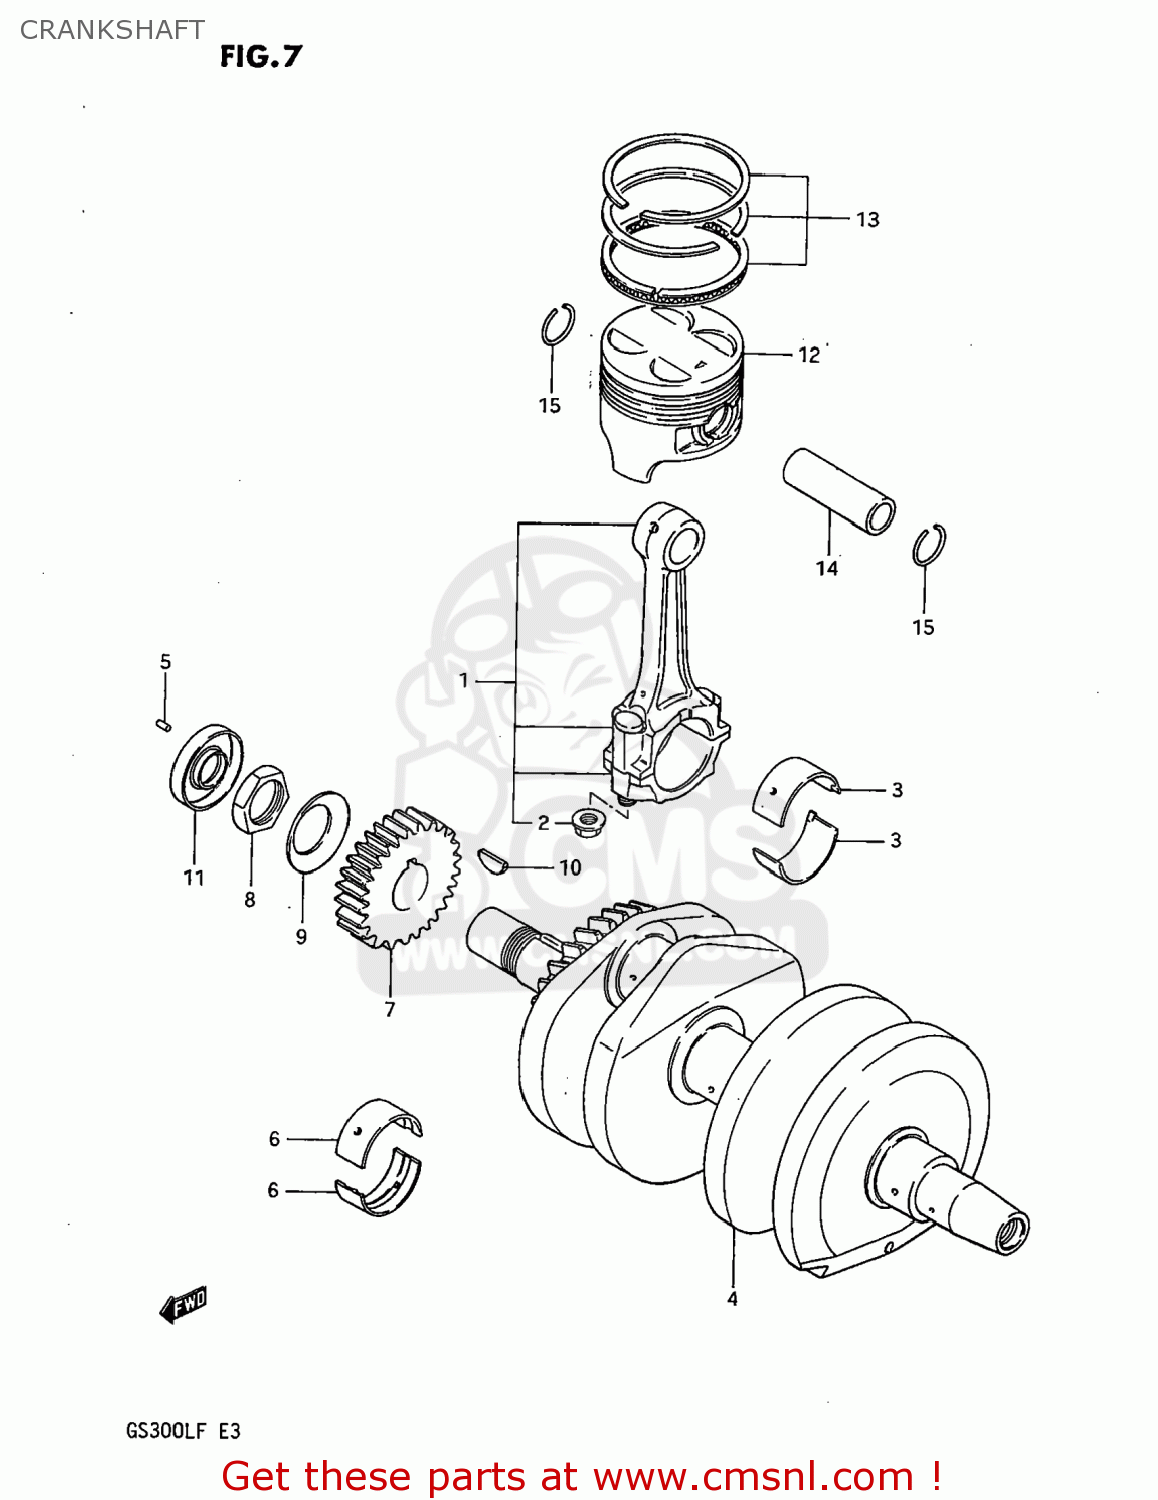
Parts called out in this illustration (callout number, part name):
1	ROD ASSEMBLY,CONNECTING
2	NUT
3	METAL,CRANK PIN
4	CRANKSHAFT
5	PIN 3X5
6	METAL CRANKSHAFT
7	GEAR,PRIMARY DRIVE
8	NUT
9	WASHER
10	KEY
11	SEAL,OIL(22X40X8)
12	PISTON (OS:0.5)
13	RING SET,PISTON
14	PIN,PISTON
15	CIRCLIP
